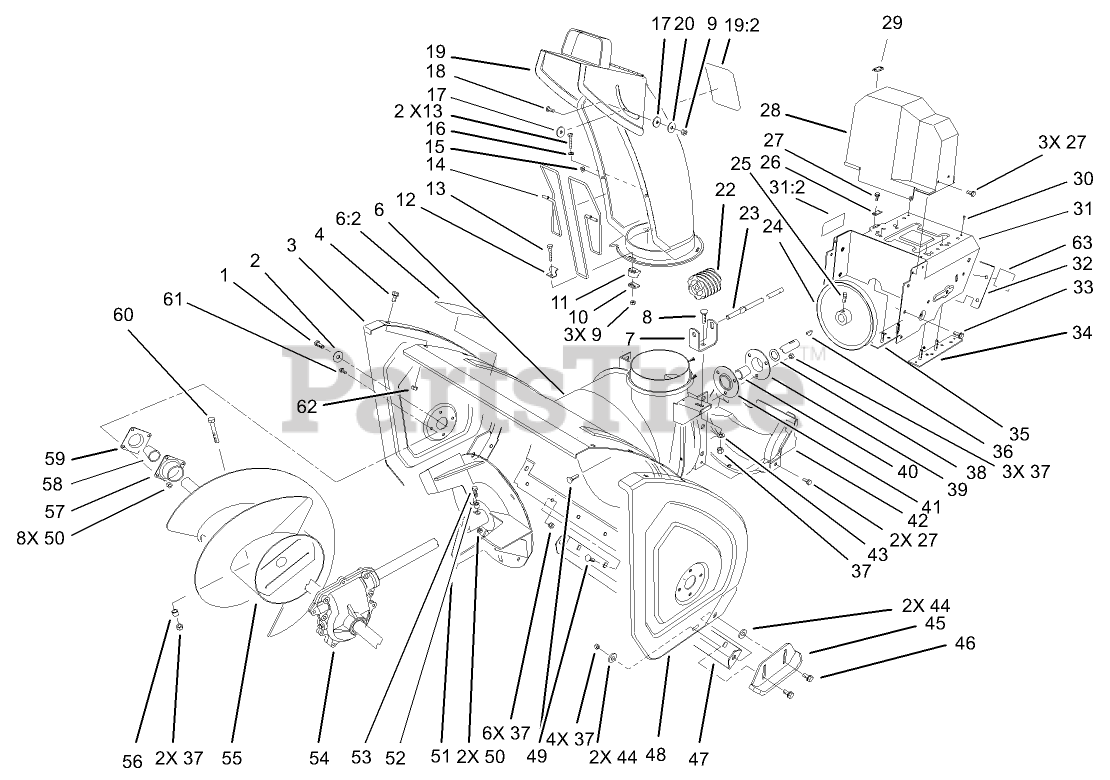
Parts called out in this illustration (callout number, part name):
1	SCREW-HH
2	WASHER
3	PLATE-SIDE, RH
4	SCREW-HHF
7	BRACKET-WORM, CHUTE
8	BOLT-CARR
9	NUT-LOCK, NI
10	PLATE-RETAINER, CHUTE
11	RETAINER-CHUTE
12	CLIP-GUARD, CHUTE
13	SCREW-HSH
14	GUARD-CHUTE
15	NUT-PUSH
16	WASHER-FLAT
17	WASHER-PLASTIC
19:2	DECAL-DANGER
20	WASHER-FLAT
22	GEAR-WORM
23	ROD-CHUTE, LOWER
25	SCREW-SET, SQH
26	RETAINER-CABLE
27	SCREW-HWH
28	COVER-BELT, UPPER
29	COVER-CABLE
30	RIVET-POP
31	ENGINE FRAME ASM
31:2	DECAL-WARNING
32	COVER-FRAME, ENGINE
33	SCREW-HWHTF
34	LH FRAME PLATE ASM
35	RH FRAME PLATE ASM
36	KEY-WOODRUFF
37	NUT-LOCK, NI
38	WASHER-THRUST
39	FLANGE-CUP, BEARING
40	BEARING-BALL
41	FLANGE-CUP, BEARING
42	COVER-BELT, LOWER
43	WASHER-PLAIN
44	WASHER
45	SKID ASM
46	SCREW-HHF
47	BLADE-SCRAPER
48	PLATE-SIDE, LH
49	SCREW-CARR
50	NUT-LOCK, NI
51	IMPELLER ASM-4 BLADE
52	SPACER
53	SCREW-HHF
54	32IN AUGER GEARCASE ASM
55	AUGER ASM-RH, 32"
56	SPACER-HUB, AUGER
57	BEARING-FLANGE, FRONT
58	BEARING
59	BEARING-FLANGE, REAR
60	SCREW-HH
61	SCREW-HH
62	NUT-LOCK, NI
63	DECAL
